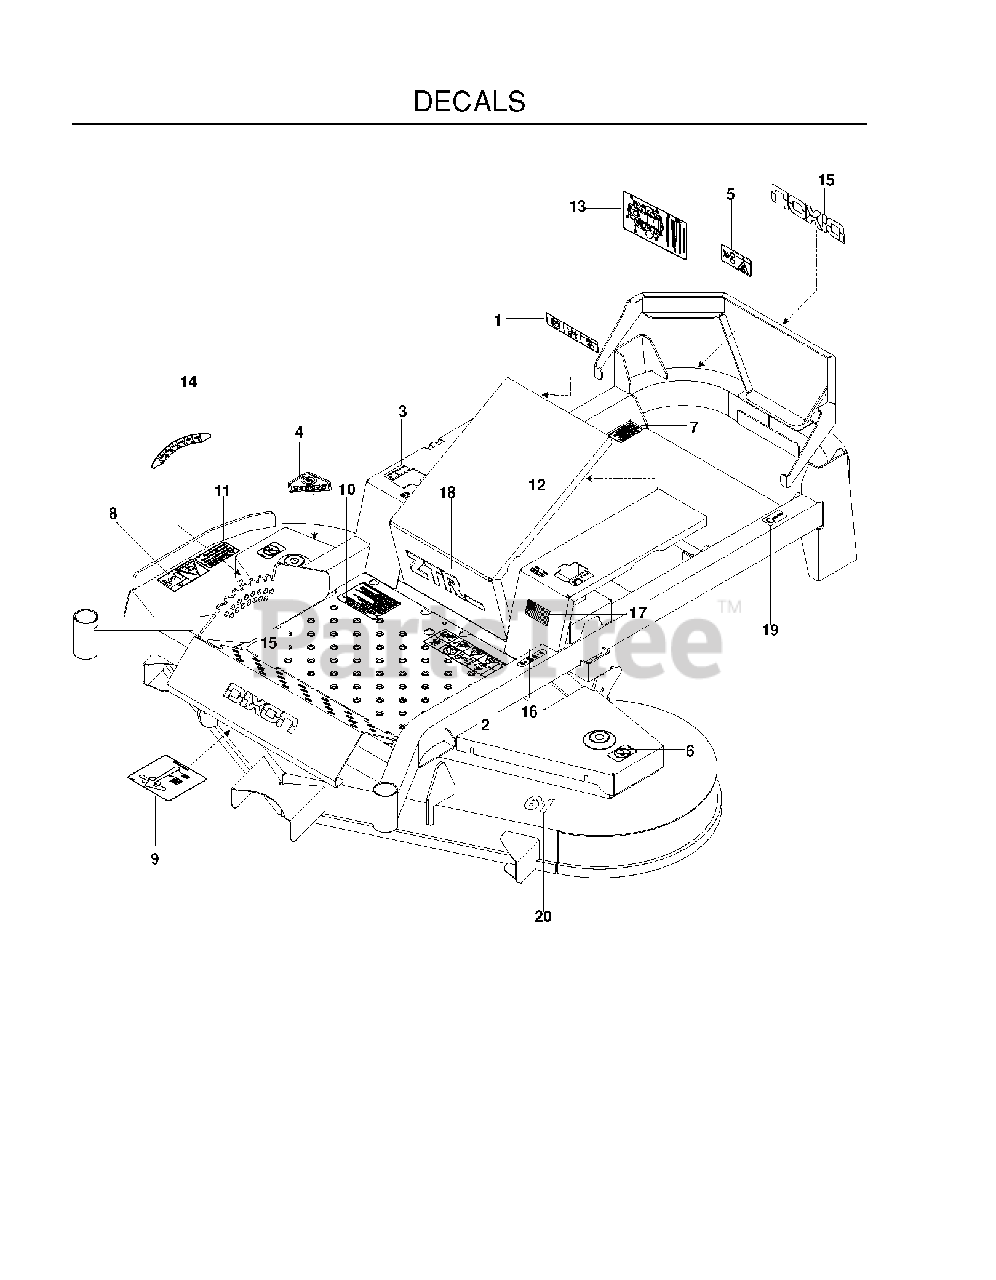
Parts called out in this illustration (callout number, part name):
1	DECAL, BATTERY
2	DECAL, WARNING
3	DECAL, MOTION CONTROL
4	DECAL, CPSC
5	DECAL, BELT DRIVE
6	DECAL, NO STEP
7	DECAL, PROP. 65
8	DECAL, EURO SEVERING
9	DECAL, BELT ROUTING
10	DECAL, WARNING
11	DECAL, CAUTION
12	DECAL, TRACKING
13	DECAL, SERVICE
14	DECAL, HEIGHT ADJUSTMENT
16	DECAL, PARK BRAKE
19	DECAL, ECM, AUSTRALIA
20	DECAL, 48
